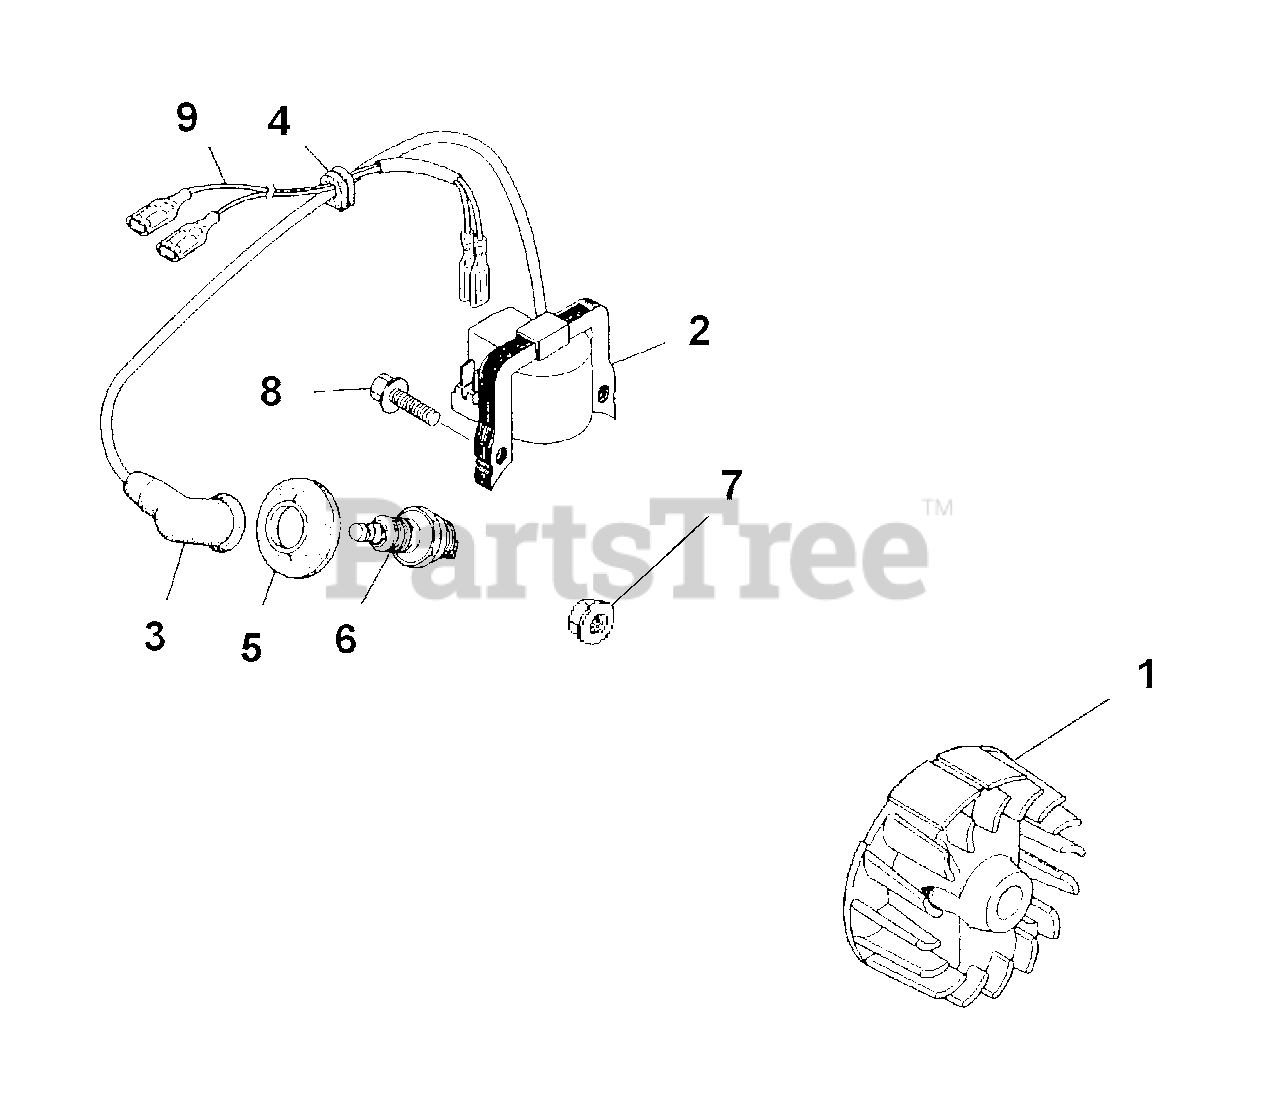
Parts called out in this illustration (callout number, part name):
2	Ignition Coil
3	Plug Cap
4	Grommet
5	Plug Cap
6	Spark Plug
7	Nut
8	Screw & Washer
9	Wire Leads
